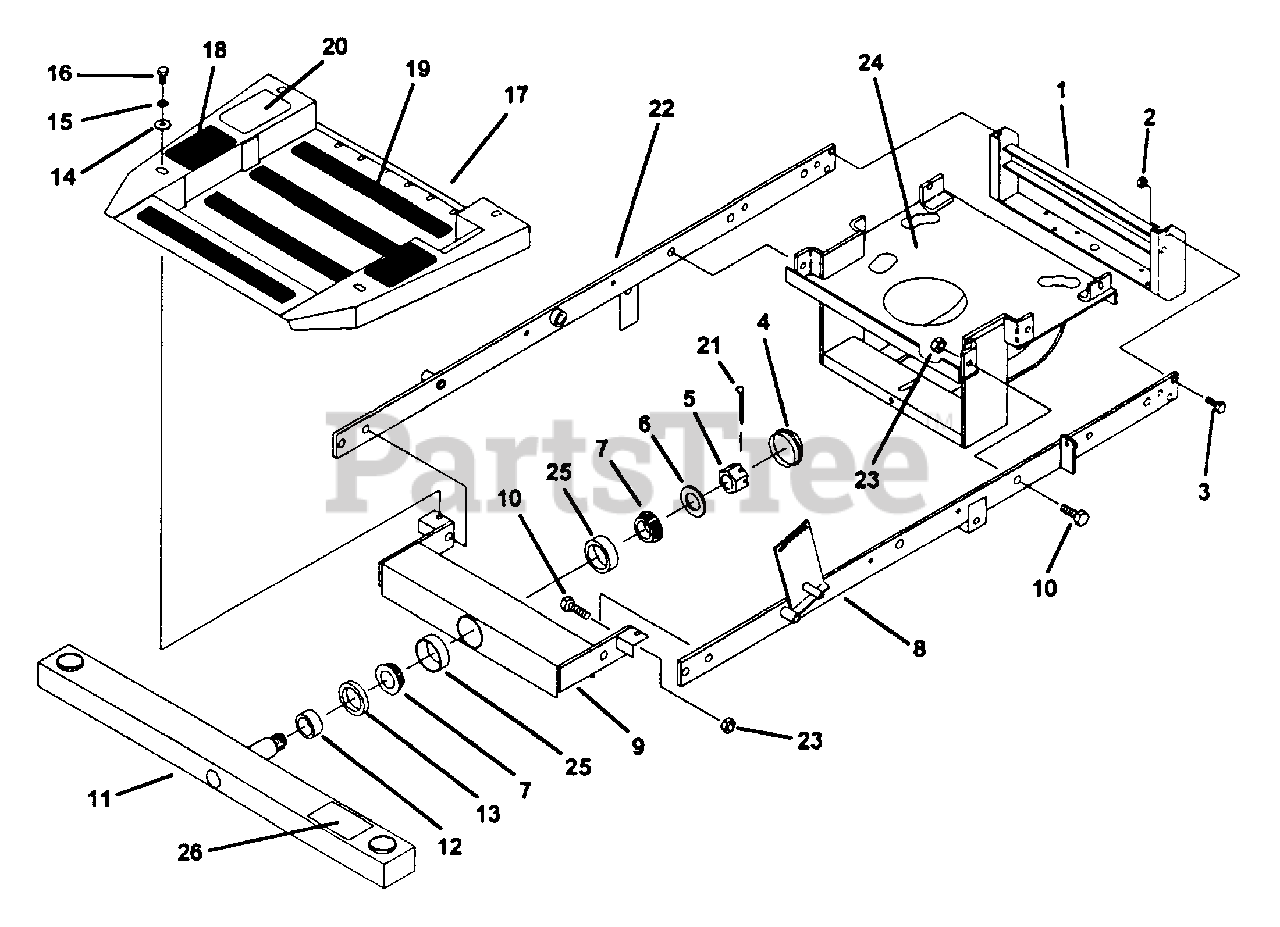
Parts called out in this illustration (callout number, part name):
1	REAR BUMPER WELDMENT
2	NUT, 3/8-16 NYLOC
3	BOLT, 3/8-16 X 1-1/4" GR.5
4	GREASE CAP
5	NUT, HEX. SLOTTED 1 "-14
6	WASHER, 1" 10 GA.
7	BEARING CONE
8	FRAME SIDE, L.H.
9	FRONT CHANNEL WELDMENT
10	BOLT, 1/2-13 X 1-1/4" GR.5
11	FRONT BUMPER/AXLE WELDMENT
12	BEARING SPACER
13	SEAL, OIL 1.688 SHAFT
14	WASHER, FLAT STD. 5/16"
15	LOCKWASHER, 5/16" HEAVY SPRING
16	BOLT, 5/16-18 X 3/4" GR. 5
17	FOOT DECK ASSEMBLY
18	TREAD PAD
19	TREAD PAD
20	DECAL, OPERATION INSTRUCTIONS
21	COTTER PIN, 3/16 X 2"
22	FRAME SIDE WELDMENT, R.H.
23	NUT, 1/2-13, STOVER
24	MOTOR MOUNT WELDMENT
25	BEARING CUP
26	DECAL, TOW WARNING
